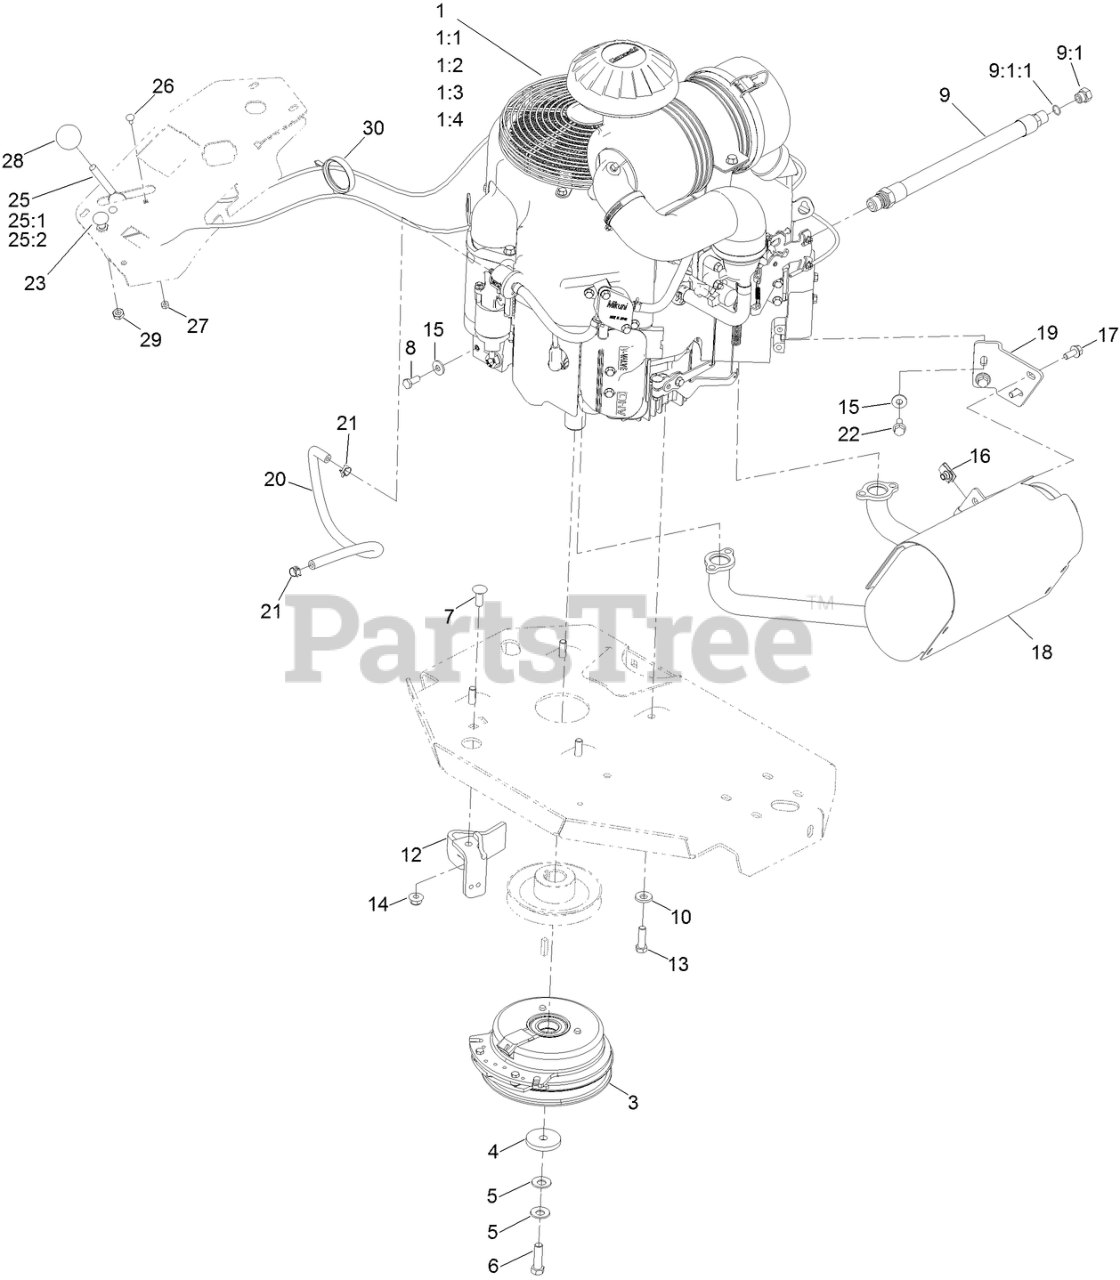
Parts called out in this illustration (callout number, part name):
1:1	KAWASAKI 49065-2078 ENGINE OIL FILTER
1:2	KAWASAKI 49019-0031 FUEL FILTER
1:3	KAWASAKI 11013-7039 SAFETY FILTER
1:4	KAWASAKI 11013-7038 AIR FILTER
3	CLUTCH KIT
4	WASHER-CLUTCH
5	WASHER-SPRING
6	SCREW-HH, W/LOCTITE
7	SCREW-CARR
8	SCREW-HH
9	ENGINE OIL DRAIN HOSE ASM
9:1	PLUG-HH
9:1:1	O-RING
10	WASHER-BELLEVILLE
12	CLUTCH-ANCHOR
13	SCREW-HH
14	NUT-HF, NI
15	WASHER-SPRING
16	NUT-U
17	SCREW-HHF
18	KIT, MUFFLER
19	BRACKET-MUFFLER
20	HOSE-FUEL
21	CLAMP-HOSE
22	SCREW-HHF
23	CONTROL-CHOKE
25	THROTTLE CONTROL ASM
25:1	LEVER-THROTTLE
26	BOLT-CARR
27	NUT-LOCK, NI
28	KNOB-BALL
29	NUT-HJ
30	CLAMP-HARNESS
